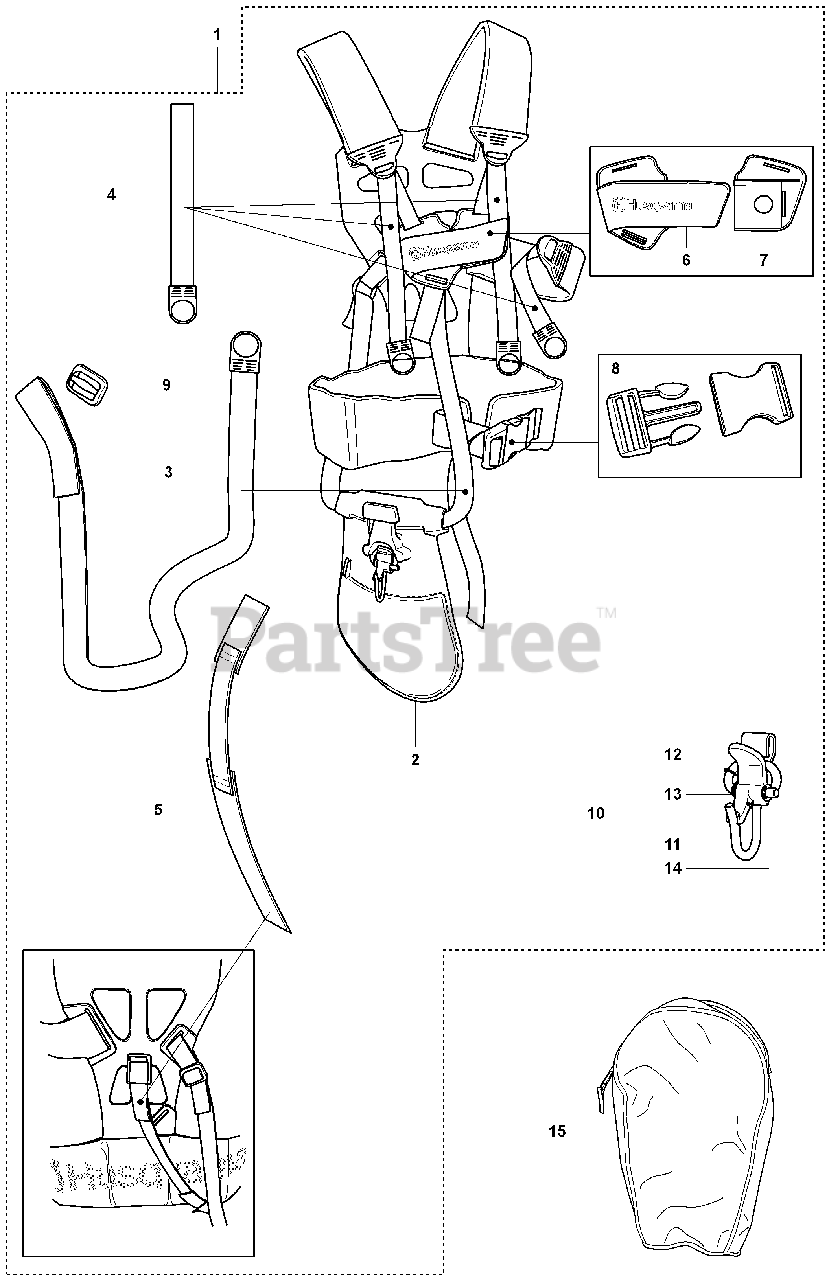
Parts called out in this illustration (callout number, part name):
6	FRONT PIECE
7	FRONT PIECE
9	RP CLIP
11	HOOK
12	CATCH *
13	SPRING
15	TOOL BAG
